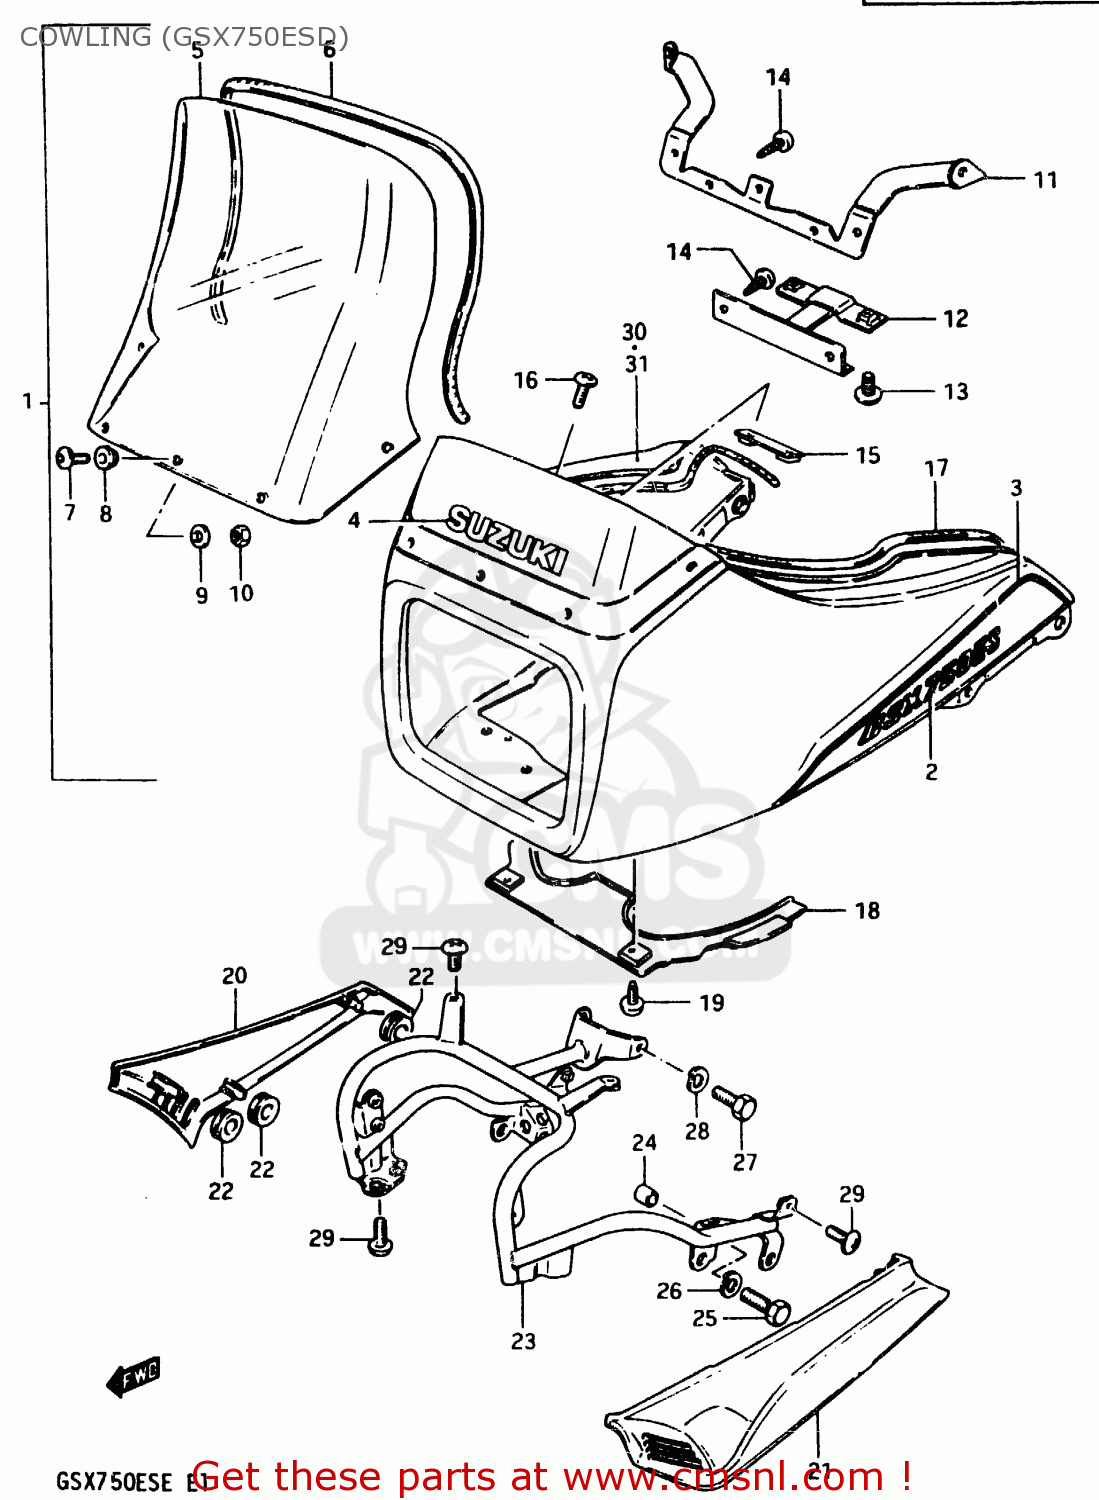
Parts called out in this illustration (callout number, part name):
1	COWLING ASSY (SILVER/RED)
2	EMBLEM, SIDE
3	TAPE SET
4	EMBLEM,HEADLAMP
5	WINDOW
6	MOLDING
7	SCREW
8	CUSHION
9	WASHER
10	NUT
11	BRACE,COWLING,UPPER
12	BRACE,COWLING,LOWER
13	SCREW RH & LH
14	SCREW
15	BRACKET
16	SCREW
17	MOLDING,FUEL TANK
18	COVER,COWLING,LOWER
19	SCREW
20	COVER, RH (RED)
21	COVER, LH (RED)
22	CUSHION
23	BRACE,COWLING
24	SPACER,COWLING
25	BOLT (8X30)
26	LOCK WASHER
27	BOLT
28	LOCK WASHER
29	SCREW 6X12
30	TAPE,RIGHT
31	TAPE,LEFT
